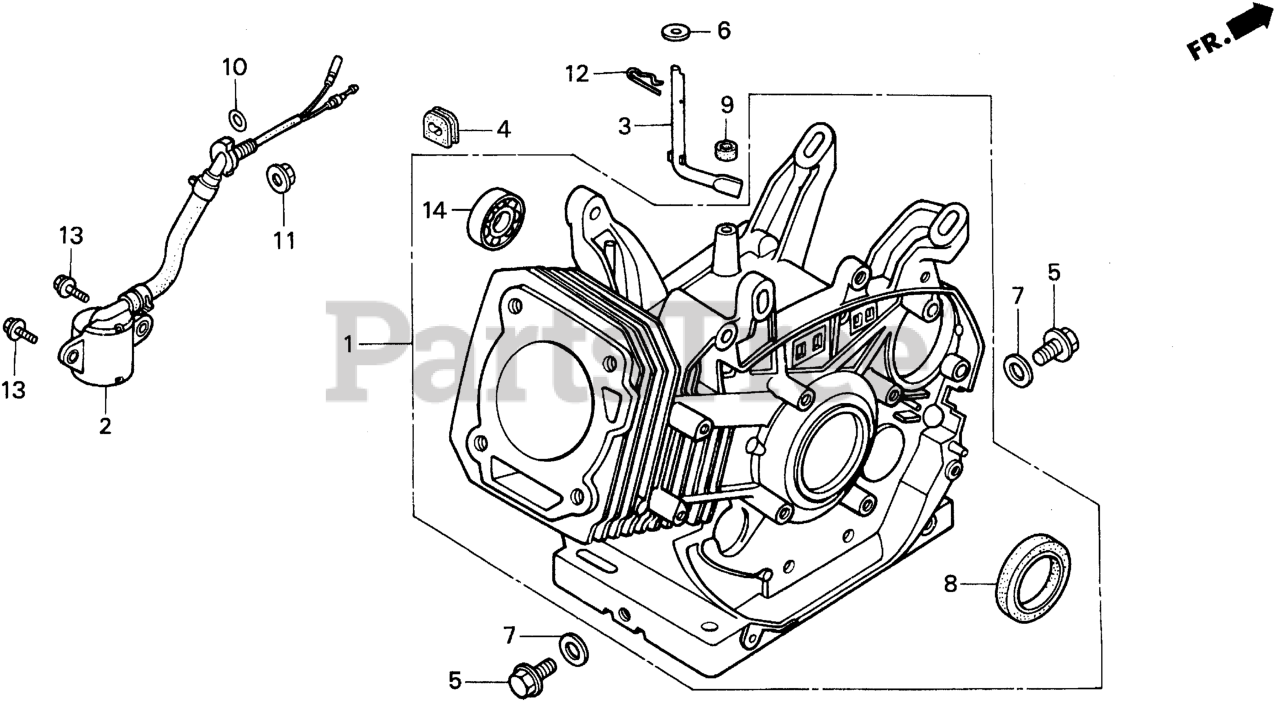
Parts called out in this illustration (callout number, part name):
1	CYLINDER ASSY. (ALERT)
2	SWITCH ASSY., OIL LEVEL
3	SHAFT, GOVERNOR ARM
4	GROMMET, WIRE
5	BOLT, DRAIN PLUG
6	WASHER (8.2X17X0.8)
7	WASHER, DRAIN PLUG (12MM)
8	OIL SEAL (35X52X8)
9	OIL SEAL (8X14X5)
10	O-RING (14MM) (ARAI) Use up to Engine SN 2949254.
11	NUT, FLANGE (10MM)
12	PIN, LOCK (8MM)
13	BOLT, FLANGE (6X12) Use up to Engine SN 1543277.
14	BEARING, RADIAL BALL (6202)
